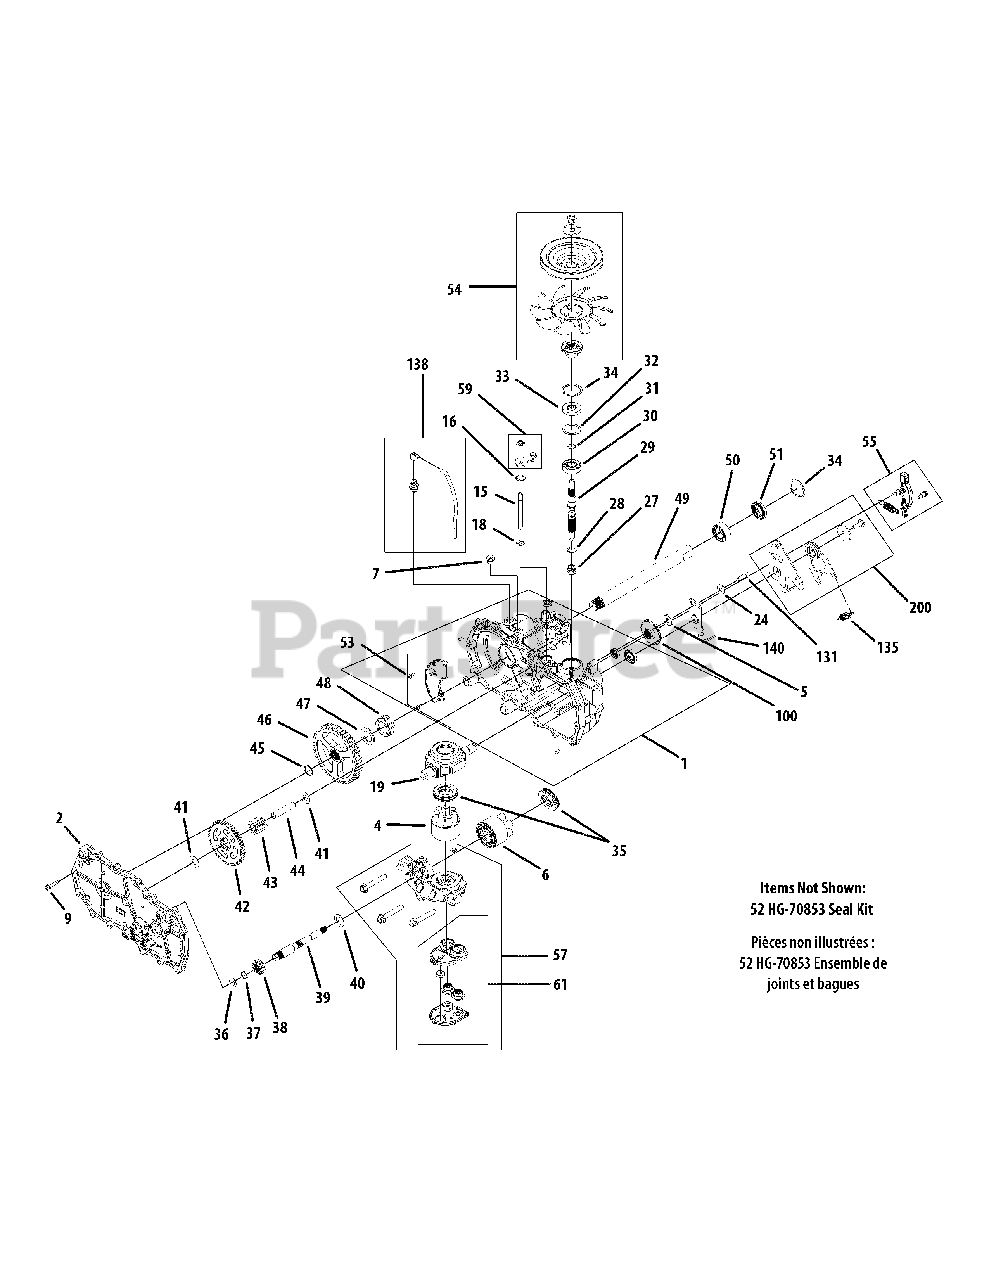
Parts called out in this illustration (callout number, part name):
1	Housing Ass’y, Main LH
2	Side Assembly LH
4	Block Kit - 7 Piston
5	Spacer, .32 x 1.005 x .179
6	Block Assembly, Cylinder
7	Straight Thread Pipe
9	Hex Washer Screw
15	Rod, Bypass
16	Retaining Ring .75 Int.
18	Retaing Ring .375 Ext.
19	Swashplate, trunnion
24	Washer .34 ID x .88 OD x .06
27	Block Washer
28	Block Thrust Washer
29	Input Shaft
30	Ball Bearing
31	Retaining Ring
32	Spacer
33	Lip Seal
34	Retaining Ring
35	Thrust Bearing
36	Flat Washer 5/8 x 1.0 x .05
37	Retaining Ring
38	Gear, Pinion, 13T
39	Shaft, Motor
40	Motor Shaft Washer
41	Washer, HT
42	Gear, 10T/48T
43	Gear, 10T Jackshaft
44	Pin, Jackshaft
45	Retaining Ring
46	Gear, Bull, 52T
47	Washer, 1.018 x 1.57 x .105
48	Sleeve Bearing
49	Shaft, Axle, 1.0 x 11.7
50	Bearing, Sleeve
51	Seal, Lip
52	Kit, Seals & Rings
53	Plate Kit, Expansion
54	Kit, Fan & Pulley
55	Kit, Brake Arm
57	Kit, Center section
59	Kit, Bypass Arm RH
61	Filter Assembly
100	Disc, Brake Cog
131	Socket Cap Screw 5/16-24 x 7/8
135	Extension Spring
138	Breather Kit
140	Neutral Arm RH
200	Kit, RTN Bidirectional
